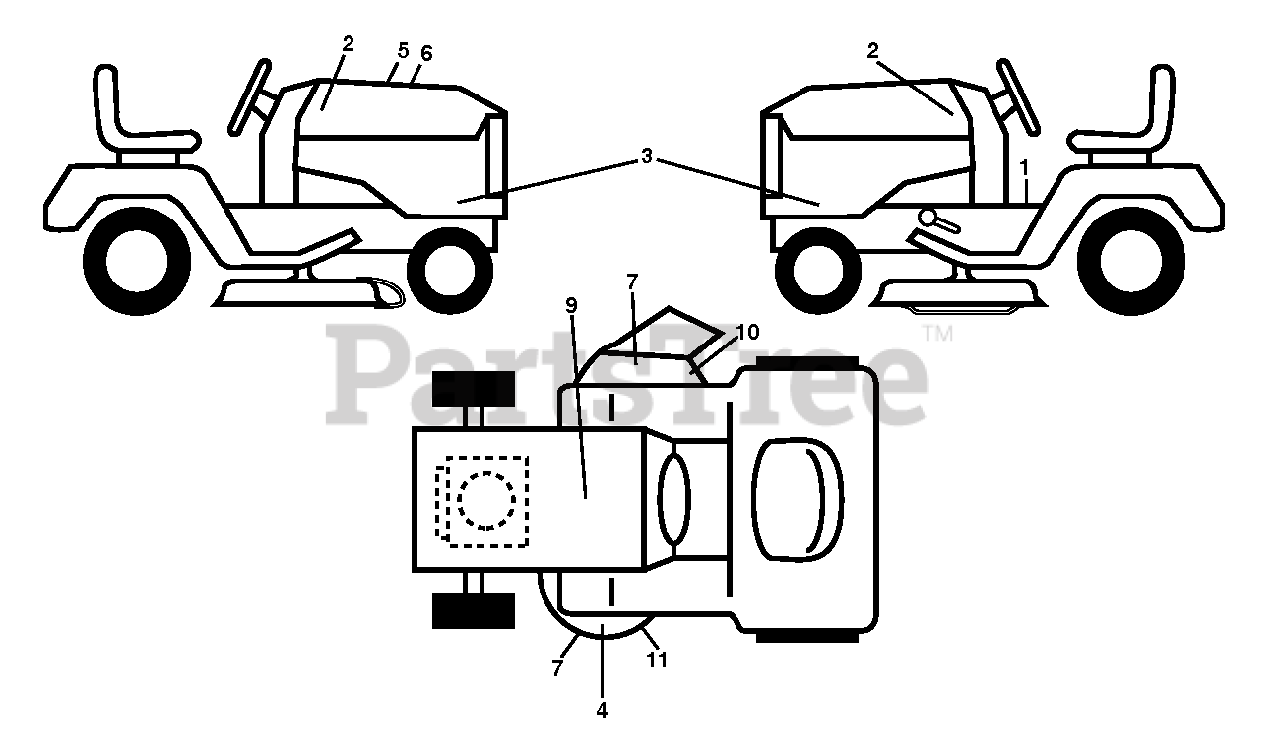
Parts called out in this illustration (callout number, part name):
1	DECAL.FENDER.WARNING.ENGLISH
2	DECAL.BADGE.170MM.TEXTLOGO.
3	DECAL.SDPNL.YT42DXLS.SET
4	DECAL.HV.REINFORCED.DECKS.2012
5	DECAL.WARNING.CUST.RESP.E85.
6	DECAL.RPL.KW.FR6.TLB.42F.K46L
7	DECAL.DECK.6MIL.EURO.NOSTEP
9	DECAL BTRY SYMBOLS
10	DECAL.TRACT/ZTR.DECKWARN.HUSQ
11	DECAL.V-BELT.SCH.42/46"MEC/ELE
